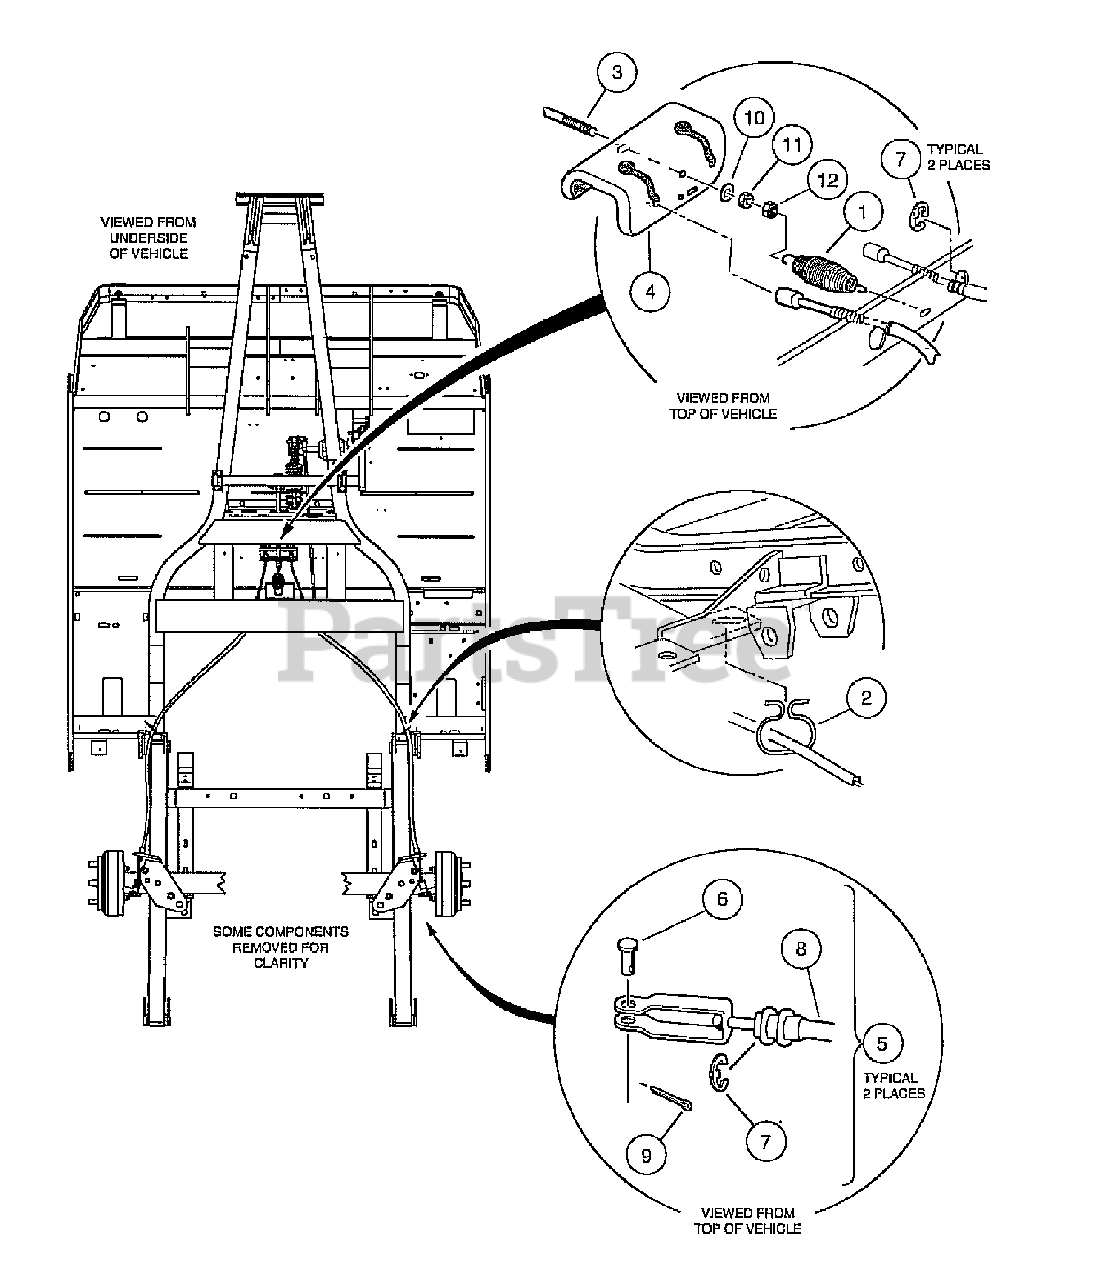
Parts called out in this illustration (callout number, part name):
1	Spring, Brake Return
2	Hanger, Brake Cable
3	Rod, Equalizer
4	Equalizer Bracket
5	Brake Cable Kit
6	Pin, Clevis, 5/16 X 3/4
7	E-Clip, 1/2
8	Cable, Brake
9	Pin, 3/32 X 1.00 5q Cut Cotter
10	Washer, 5/16 Type A Flat
11	Nut, 5/16-18 Hex
12	Locknut, 5/16-18 Nylon insert
